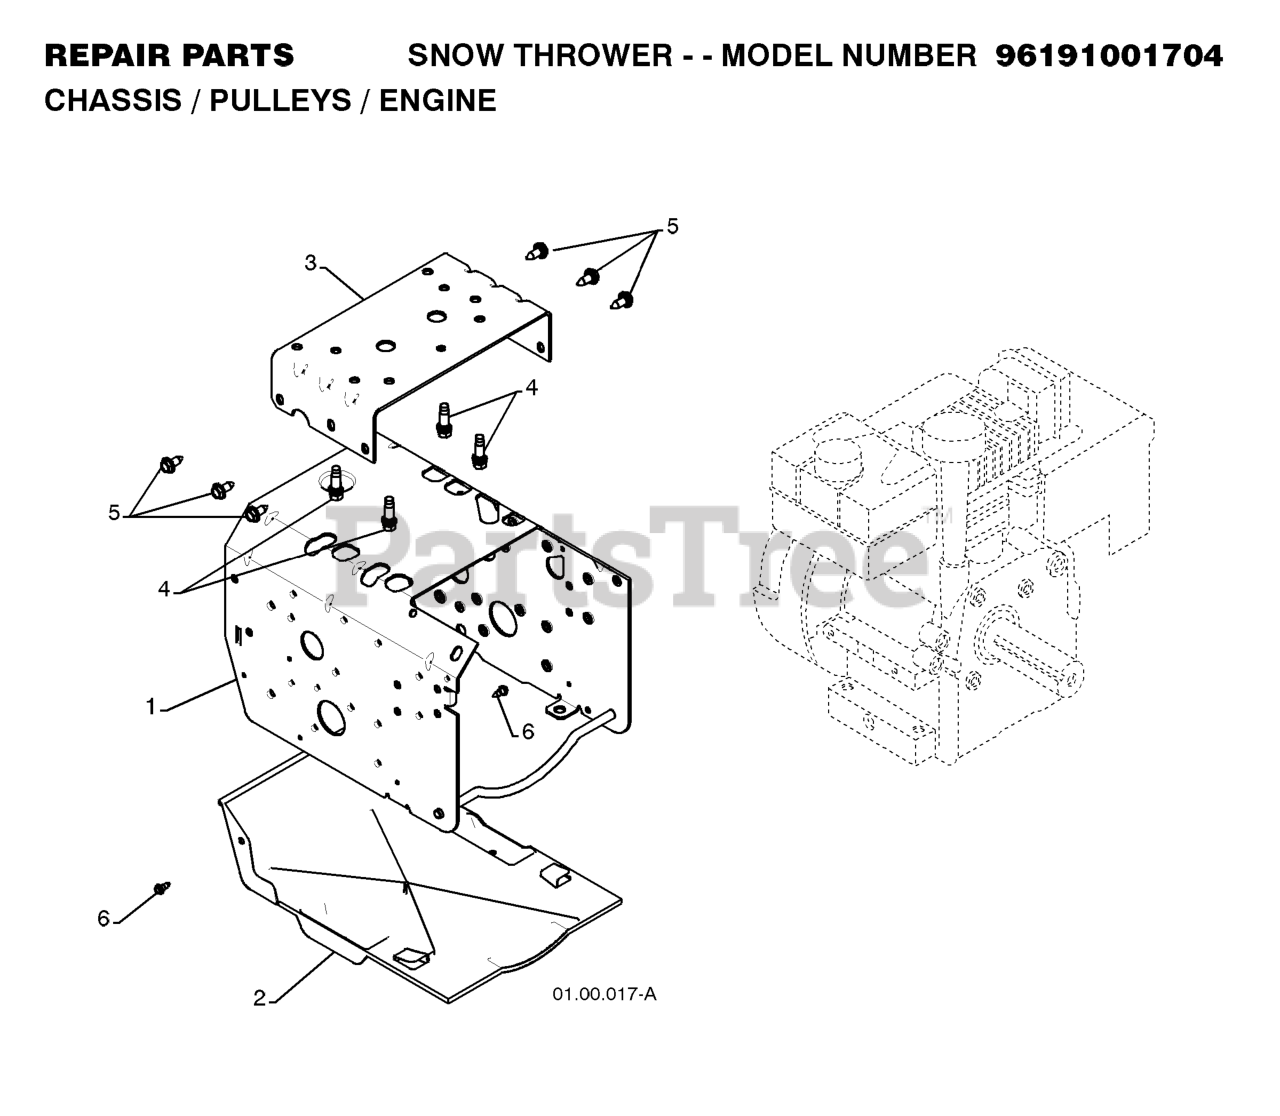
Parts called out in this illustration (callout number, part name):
1	FRAME.WELD.PNT.003BGP
2	PAN.BOTTOM.PLASTIC
3	PLATE.ENGINE.MOUNT.PNT
4	BOLT 3/8-16X1-1/8
5	SELF-TAPPING SCREW 5/16-18X3/4
6	SCREW, HEX HEAD, TAPPING
